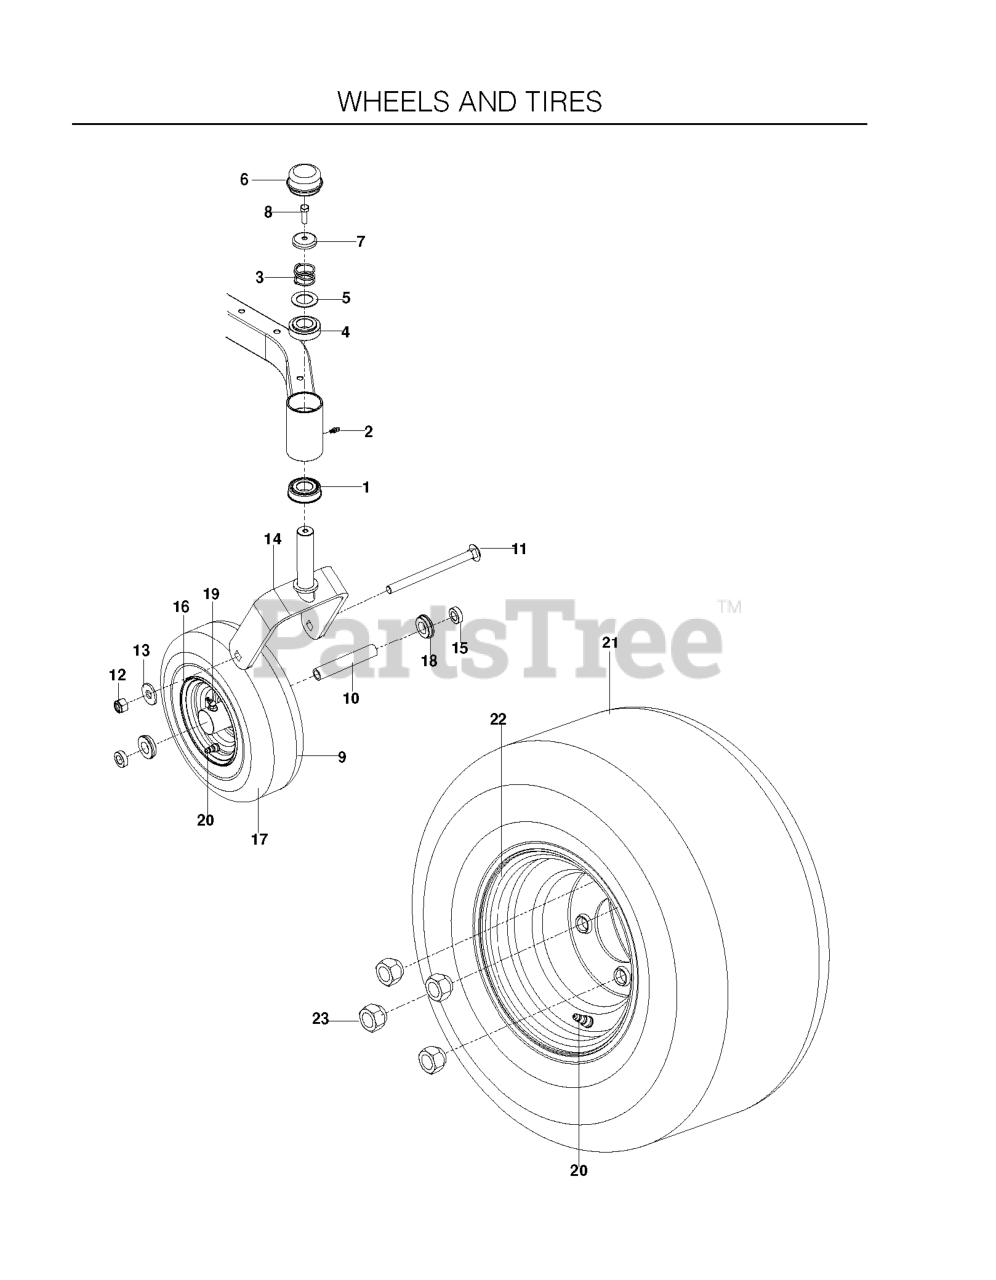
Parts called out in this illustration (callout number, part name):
1	BEARING FLANGED
2	ZERK, 3/16, DRIVE IN
3	SPRING, CASTER
4	BUSHING, CASTER
5	WASHER, 1.025 ID X 1.64
6	GREASE CAP
7	CASTER.PLUG
8	5/16-18X1 HHB G5W/NY
9	TIRE COMPLETE
11	RHSNB 1/2-13 X 6.50 GR2 ZD
12	NUT 1/2-13 HEX NYLOC ZD
13	WASH USS FLAT 1/2
14	YOKE.CASTER.ORANGE
15	SPACER, 5/16"
17	TIRE - CASTER
18	BEARING RETAINER
19	ZERK
20	VALVE STEM TR-412
21	TIRE ASM, 20 X 8-8
22	RIM.8X7.W/8".OFFSET.SILVER.ZTR
23	LUG NUT 1/2F
